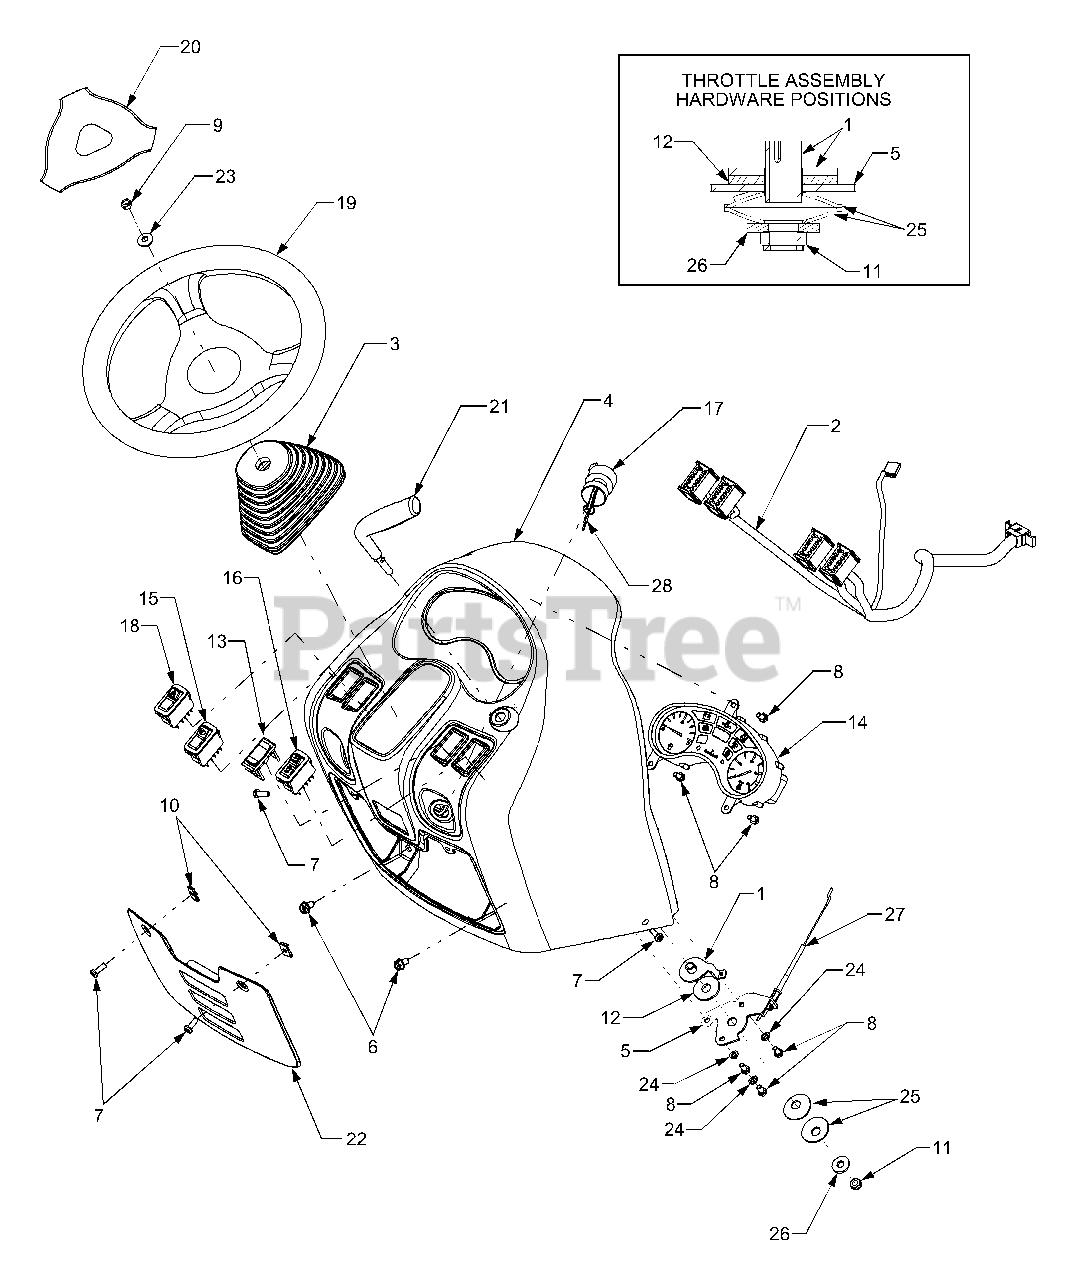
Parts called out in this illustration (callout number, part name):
3	Boot, Steering Shaft
4	Dash
5	Plate, Throttle Mtg.
6	Screw, Hex Wash. Hd. Tapp 5/16-18 x .625
7	Screw, Pan Hd., 1/4-20 x .75
8	Screw, Hex Cap, 1/4-20 x .5 GR5
9	Nut, Hex Lock, 5/16-24
10	Nut, Speed, 1/4-20
11	Nut, Hex Insert Jam Lock, 3/8-24
12	Washer, Friction, .515 x 1.5 x .12
14	Panel, Instrument
15	Switch, Headlight
16	Switch, PTO
17	Switch, Ignition
18	Switch, Hazard
19	Steering Wheel, Soft Grip
20	Cover, Steering Wheel
21	Handle, Throttle
22	Panel, Dash Insert
23	Washer, Belleville, .34 x .872 x .06
24	Washer, Lock, 1/4
25	Washer, Belleville, .531 x 1.62 x .045
26	Washer, Flat, .406 x 1.0 x .105
27	Cable, Throttle
28	Key Set, Ingition
